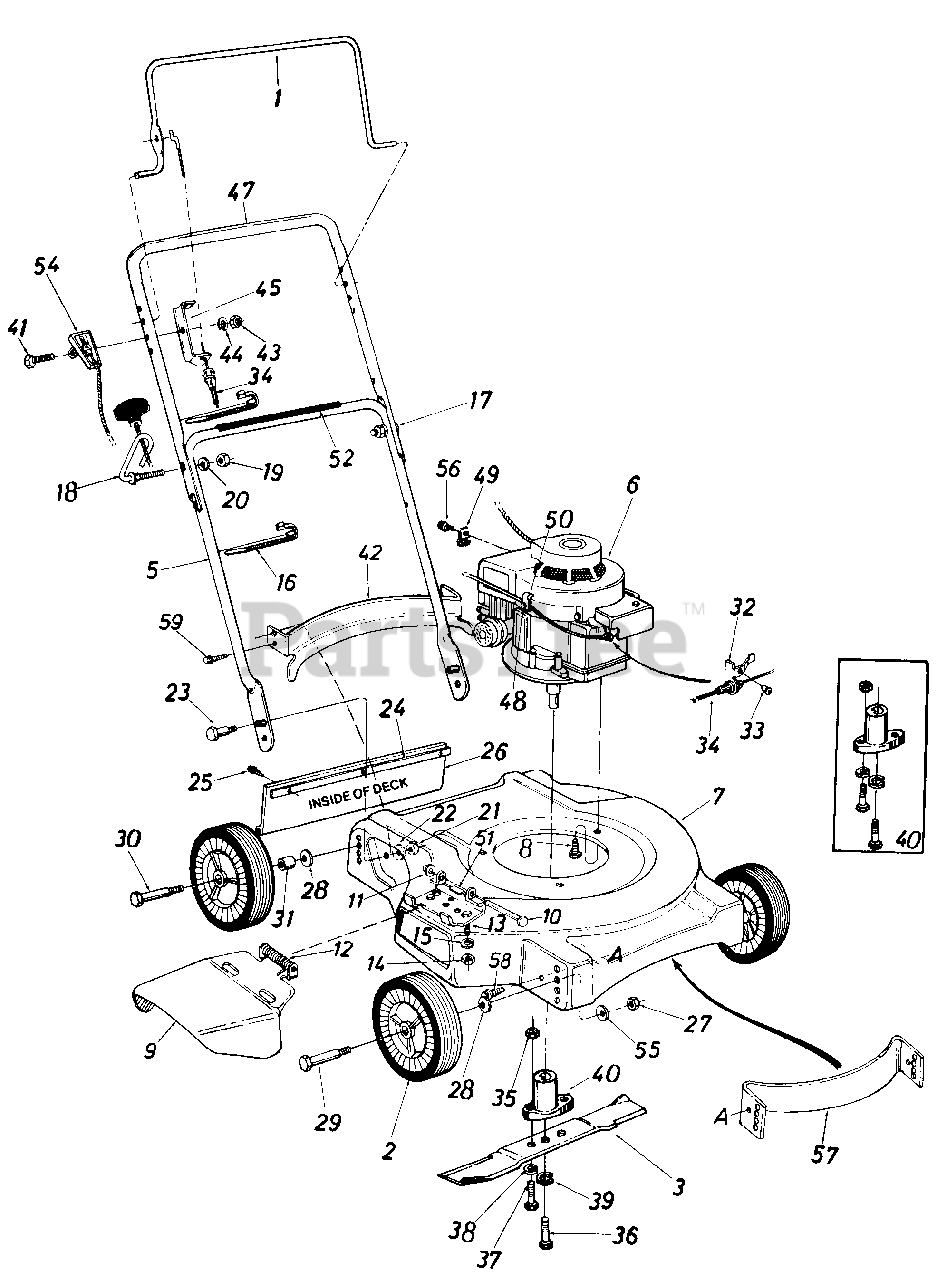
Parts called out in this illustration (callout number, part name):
1	Control Handle
2	Plastic Wheel Ass'y.
3	20" Blade
6	Engine
9	Chute Deflector Ass'y.
10	Pivot Pin
11	Cap Speed Nut 1/4" Rod
12	Torsion Spring
13	Hex Bolt 1/4-20 X .50" Lg.
14	Hex Nut 1/4-20 Thd.
15	L-Wash. 1/4" I.D.
16	Cable Tie
17	Curved Carriage Bolt 5/16-18 x 1.38" Lg.
18	Rope Guide Bolt
19	Hex Nut 5/16-18 Thd.
20	L-Wash. 5/16" I.D.*
21	Hex Ins. L-Nut 5/16-18 Thd.
22	Bell-Wash. .345" I.D. x .88" O.D.
23	Shld. Bolt .437" Dia. x .180" Lg.
24	Retainer Strip
25	Hex Wash. Hd. Self-Tap Scr. 1/4" X .62" Lg.
26	Rear Flap Ass'y.
27	Hex Nut 3/8-16 Thd.*
28	Bell-Wash. .400" I.D. x .88" O.D.
29	Shld. Bolt
30	Shld. Bolt
31	Spacer
32	Cable Bracket
33	Pop Rivet .156" Dia. x .379
34	Control Cable 43.0" Lg.
35	Hex Nut 5/16-24 Thd.*
36	Hex Bolt 3/8-24 x 1.00" Lg. (Grade 5)
37	Hex Bolt 5/16-24 x 1.00" Lg. (Grade 5)
38	L-Wash. 5/16" I.D.*
39	L-Wash. 3/8" l.D. Heavy Duty
40	Blade Adapter Kit
41	Hex Bolt 1/4-28 x 1.75" Lg.
42	Rear Baffle
43	Hex Nut 1/4-28 Thd.
44	L-Wash. 1/4" I.D.
45	Cable Mounting Brkt.
47	Upper Handle
48	Hex B-Tap Scr. #10 x .38"-Lg.
49	Casing Clamp
50	Casing Clamp
51	Hinge Plate
52	Instruction Label Handle
54	Throttle Controi Ass'y. Comp.
55	Bell-Wash. .39" I.D. x 1.13" O.D.
56	Hex AB-Tap Scr. #8 x .38"-Lg.
57	Baffle
58	Hex B-Tap Screw 1/4 x .38"-Lg.
59	Hex Tap Screw #10 x .50" Lg.
